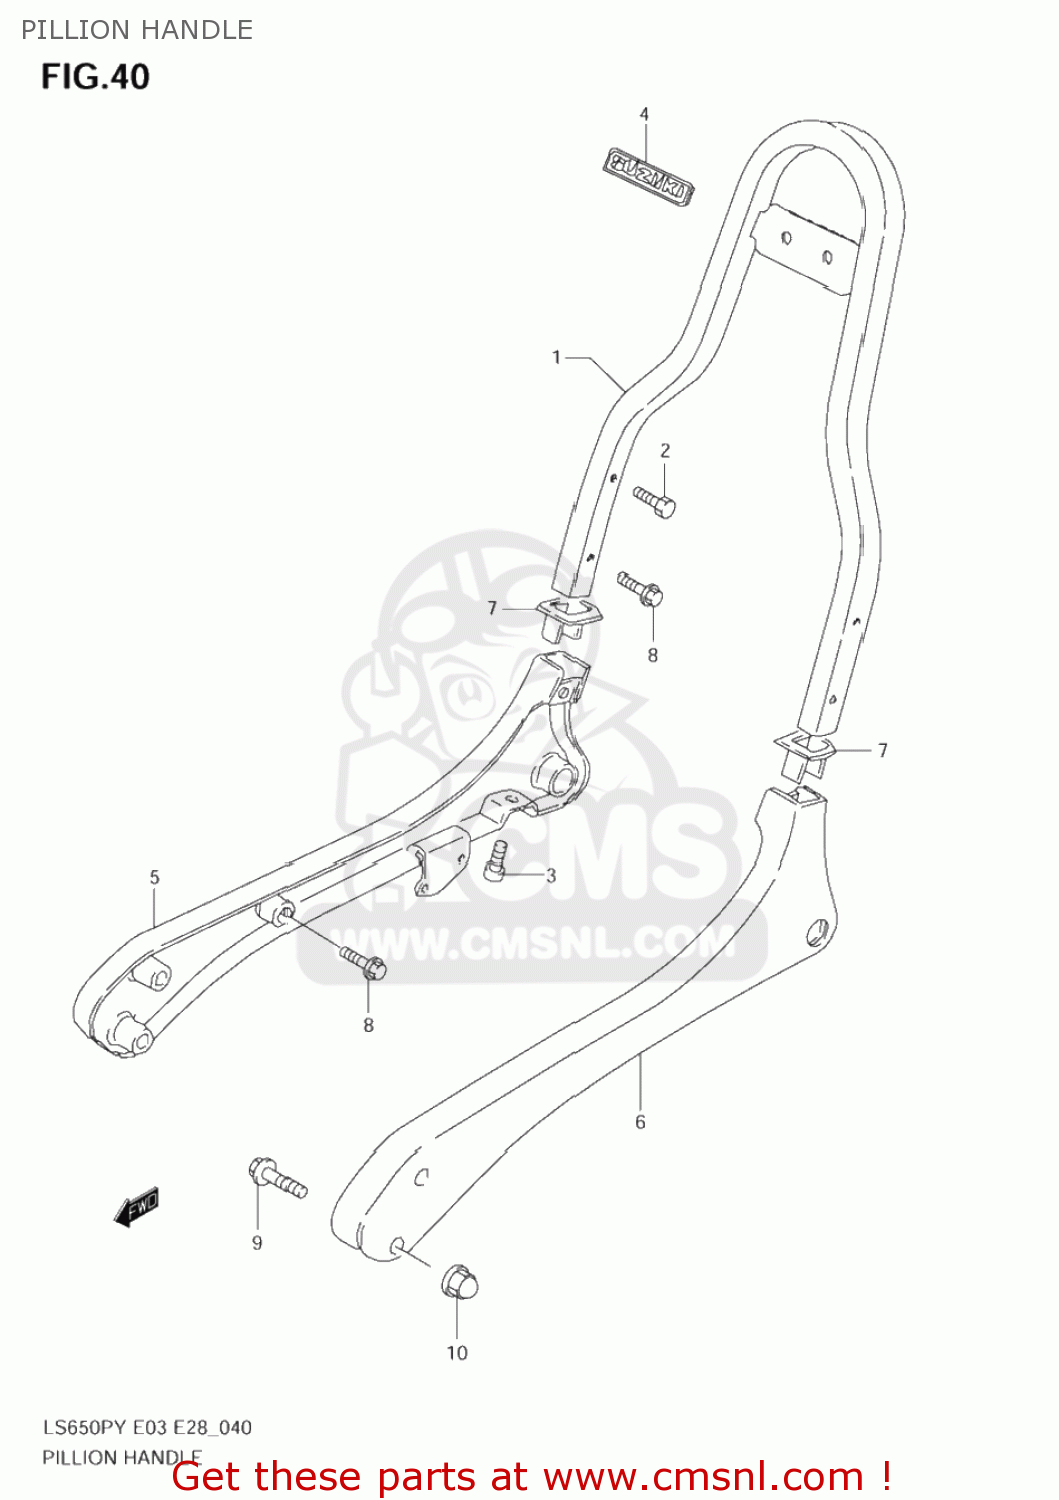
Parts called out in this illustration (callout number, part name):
1	HANDLE,PILLION UPR
2	BOLT
3	PLUG
4	EMBLEM
5	HANDLE,PILLION RIDER,R
6	HANDLE,PILLION RIDER,L
7	COVER,PILLION HNDL
8	BOLT
9	BOLT
10	NUT
